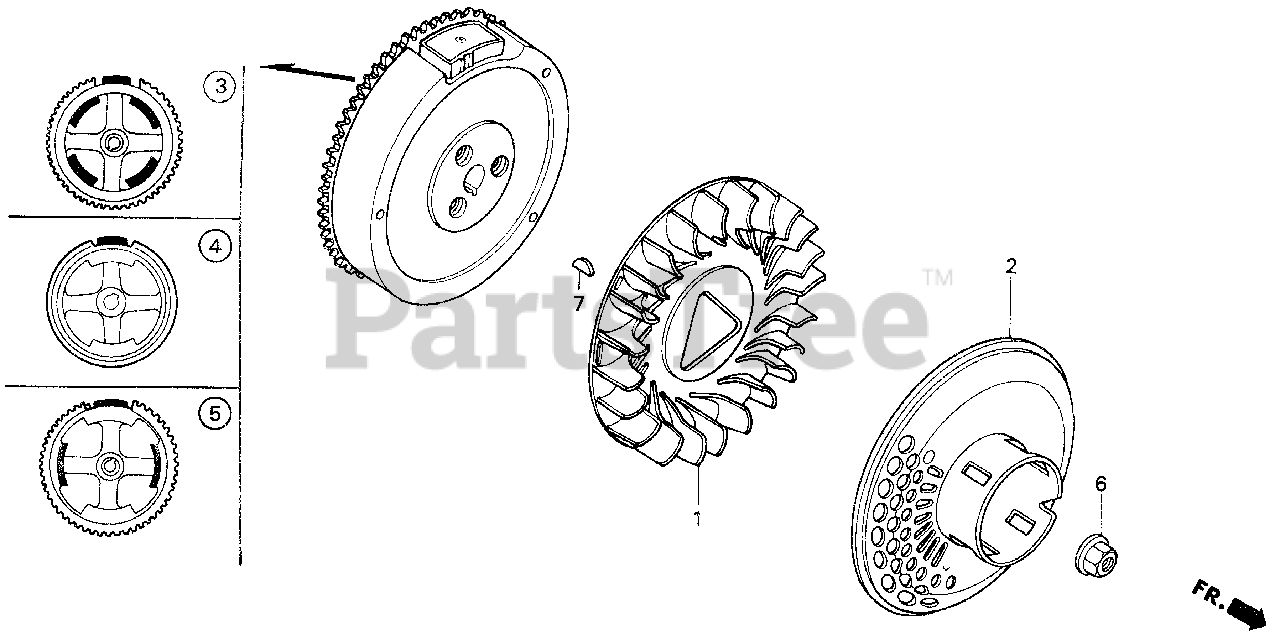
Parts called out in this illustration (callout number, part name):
1	FAN, COOLING
2	PULLEY, STARTER (SCREEN GRID)
4	FLYWHEEL
6	NUT, SPECIAL (16MM) (1)
6	NUT, SPECIAL (16MM)
7	KEY, SPECIAL WOODRUFF (25X18)
